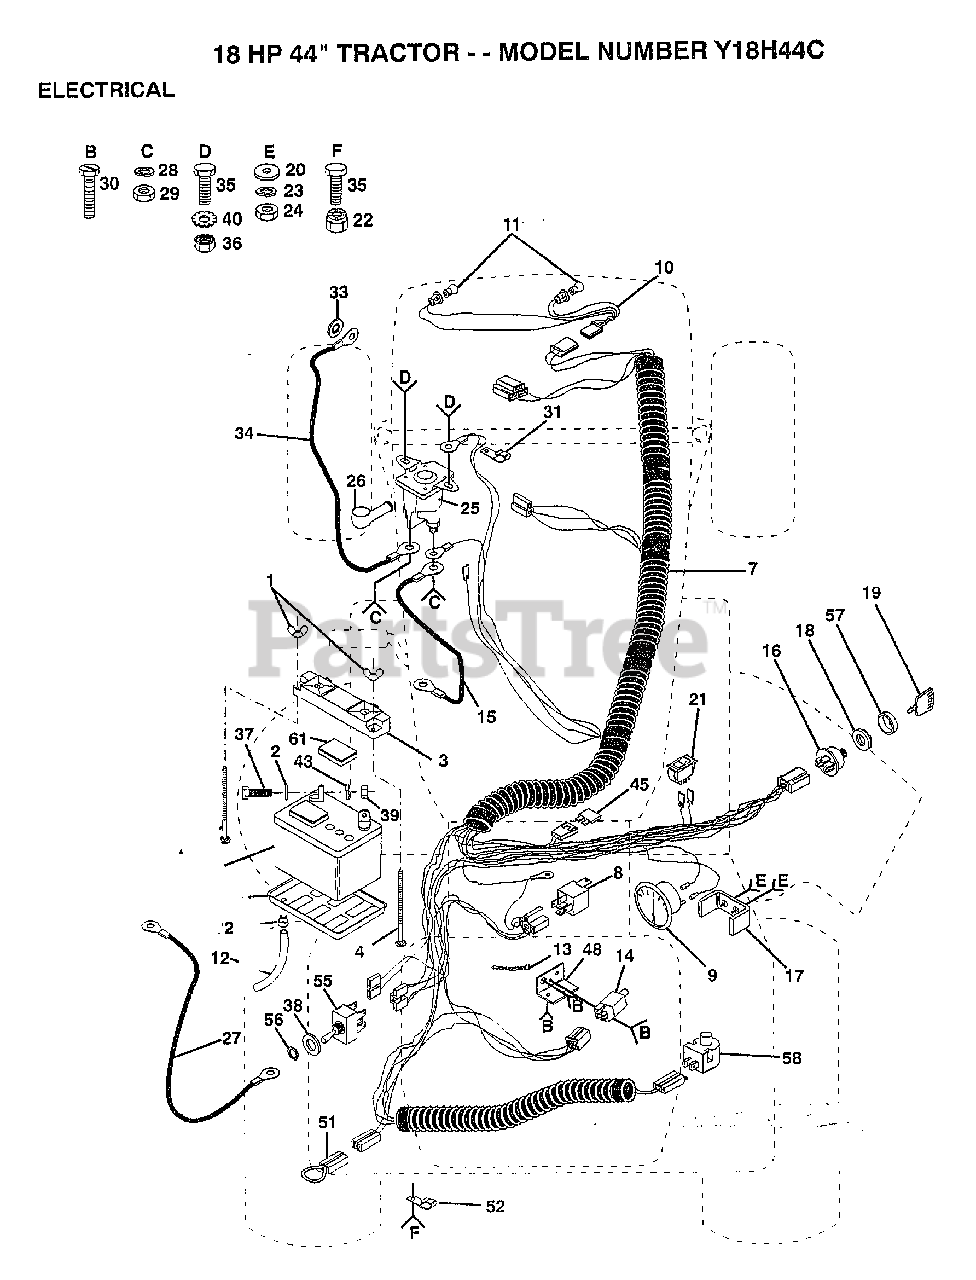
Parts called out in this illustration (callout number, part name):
2	WASHER
4	BOLT
6	"TRAY T, BATTERY"
8	RELAY ASSY T
9	AMMETER T
10	"HARNESS,LIGHT SOC"
12	"DRAIN TU T, BATT"
13	WIRE TIE
14	SWITCH INTERLOCKT
15	CABLE-BATTERY T
18	NUT IGNITION
19	KEY
20	WASHER
21	SWITCH LT
27	CABLE T
29	NUT
30	SCREW
31	CLIP T
32	HOSE CLAMP T
33	LOCKWASHER
34	"CABLE T, BATTERY"
35	BOLT
36	NUT
37	BOLT LT
38	WASHER
43	LOCKWASHER
45	FUSE HYT
48	BRACKET LT
52	CLIP, INSULATED
56	HEX NUT T
58	SWITCH SEAT
61	"CAP,BATTERY "
